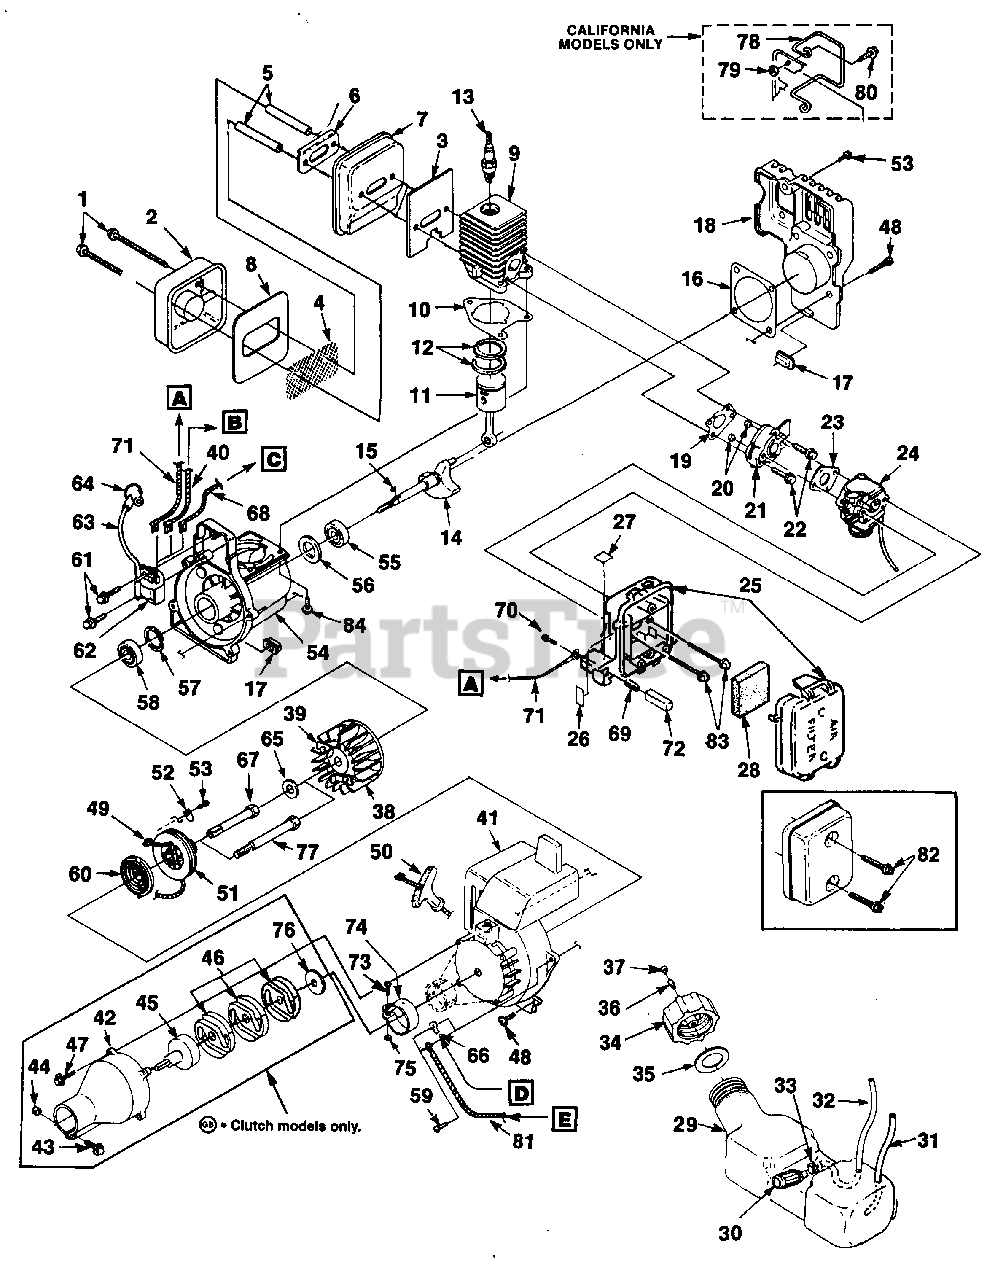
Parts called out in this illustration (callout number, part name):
1	SCREW- Hex hd. (10-24 x 2 1/2")
2	MUFFLER- Cover
3	GASKET- Muffler
4	SCREEN- Spark
5	SPACER- Muffler
6	PLATE- Reinforcing
7	BODY- Muffler
8	BAFFLE- Muffler
9	CYLINDER
10	GASKET
11	PISTON & ROD ASSY.
12	RING- Piston
13	SPARK PLUG (DJ7Y)
14	CRANKSHAFT
15	KEY- Woodruff
16	GASKET- Crankcase
17	BUMPER- Rubber
18	COVER- Crankcase
19	GASKET- Heat dam
20	NUT- (10-24)
21	HEAT- Dam
22	SCREW- Thd. form (10-24 x 1")
23	GASKET- Carburetor
24	CARBURETOR (Walbro)
25	AIR FILTER BOX & COVER
26	DECAL- Choke/Run
27	DECAL- Push/hold
28	AIR FILTER
29	TANK- Fuel
30	FILTER- Fuel
31	TUBING- Rubber (8")
32	TUBING- Rubber (8")
33	CLAMP- Wire
34	FUEL- CAP ASSY.
35	GASKET- Fuel cap
36	FILTER
37	VALVE- Filter
38	ROTOR & STARTER PAWL
39	STARTER PAWL KIT
40	LEAD- Electrical (HLT-17C & HBC-18)
41	HOUSING- Engine (HLT-16 & HLT-18)
42	TUBE ADAPTOR KIT (HLT-17C, HBC-18, HBC-30 & HBC-30B)
43	SCREW
45	CONNECTOR & DRUM (HLT-17C)
46	CLUTCH (HLT-17C) (HBC-18, HBC-30 & HBC-30B)
47	SCREW (10-24 x 7/8") (HLT-17C, HBC-18, HBC-30 & HBC30B)
48	SCREW (10-24 x 3/4") (HLT-17C, HBC-18, HBC-30 & HBC-30B)
49	ROPE- Starter
50	GRIP- Starter
51	PULLEY- Starter
52	BRACKET- Retaining
53	SCREW- Plastite
54	CRANKCASE ASSY.
55	BEARING-Ball
57	RING-Retaining
58	BEARING- Ball
59	SCREW- Truss hd. (10-24 x 3/4")
60	SPRING & CONTAINER
61	SCREW- Taptite
62	MODULE- Ignition (Sems-Walbro)
63	LEAD- High tension
64	TERMINAL- High tension
65	WASHER (HLT-16 & HLT-18)
66	TERMINAL (HBC-30 & HBC-30B)
67	DRIVE CONNECTOR (HLT-16 & HLT-18)
68	LEAD- Electrical (HBC-30 & HBC-30B)
69	SPRING- Compression (HLT-16 & HLT-18)
70	SCREW- Plastite (#6) (HLT-16 & HLT-18)
71	LEAD- Electrical (HLT-16 & HLT-18)
72	BUTTON- Switch (HLT-16 & HLT-18)
73	SCREW-Hex sems (10-24 x 3/8") (HLT-16 & HLT-18)
74	CLAMP (HLT-16 & HLT-18)
75	NUT- Square (HLT-16 & HLT-18)
76	WASHER- Flat (HLT-17C, HBC-18, HBC-30 & HBC-30B)
77	ADAPTOR- Clutch (HLT-17C)
78	WIRE GUARD KIT (California Models Only)
79	NUT (10-24)
80	SCREW (10-24 x 1/2")
81	LEAD- Ground (HLT-17C & HBC-18)
82	SCREW
83	SCREW (10-24 x 2 1/4")
84	SCREW (10-24 x 3/4") (T-27)
